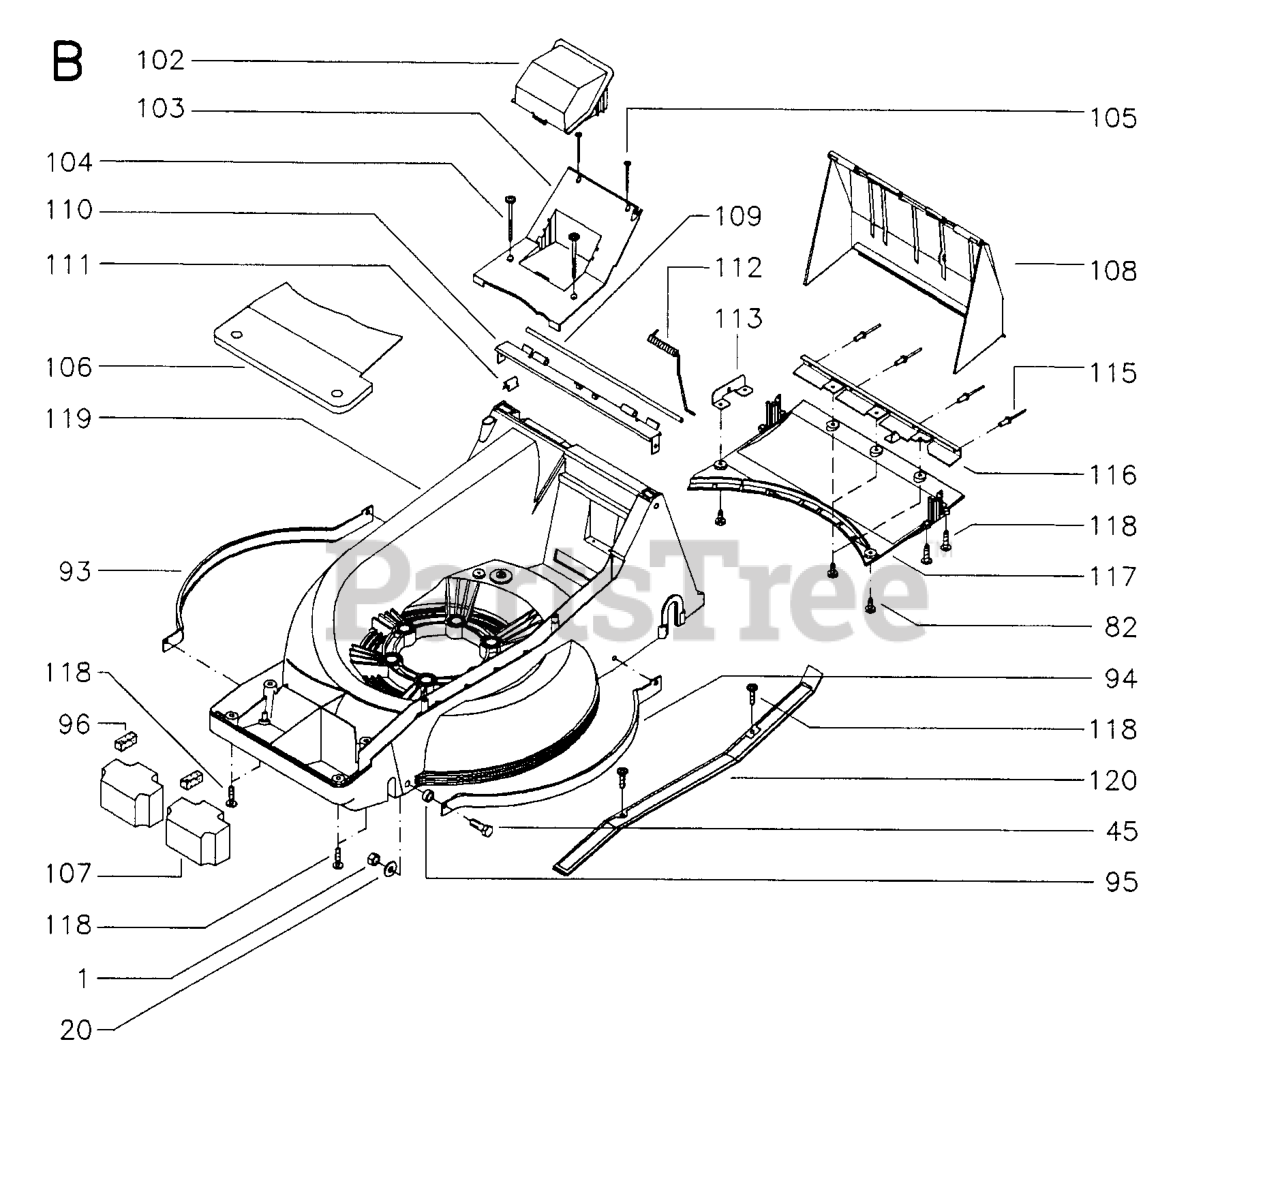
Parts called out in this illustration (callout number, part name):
1	LOCKNUT M8
45	SCREW M6S 8X25
93	DECK PROTECTOR RH
94	DECK PROTECTOR LH
106	DECK FRONT COVER
107	COUNTERWEIGHT
110	BRACKET
113	BRACKET
120	COVER
